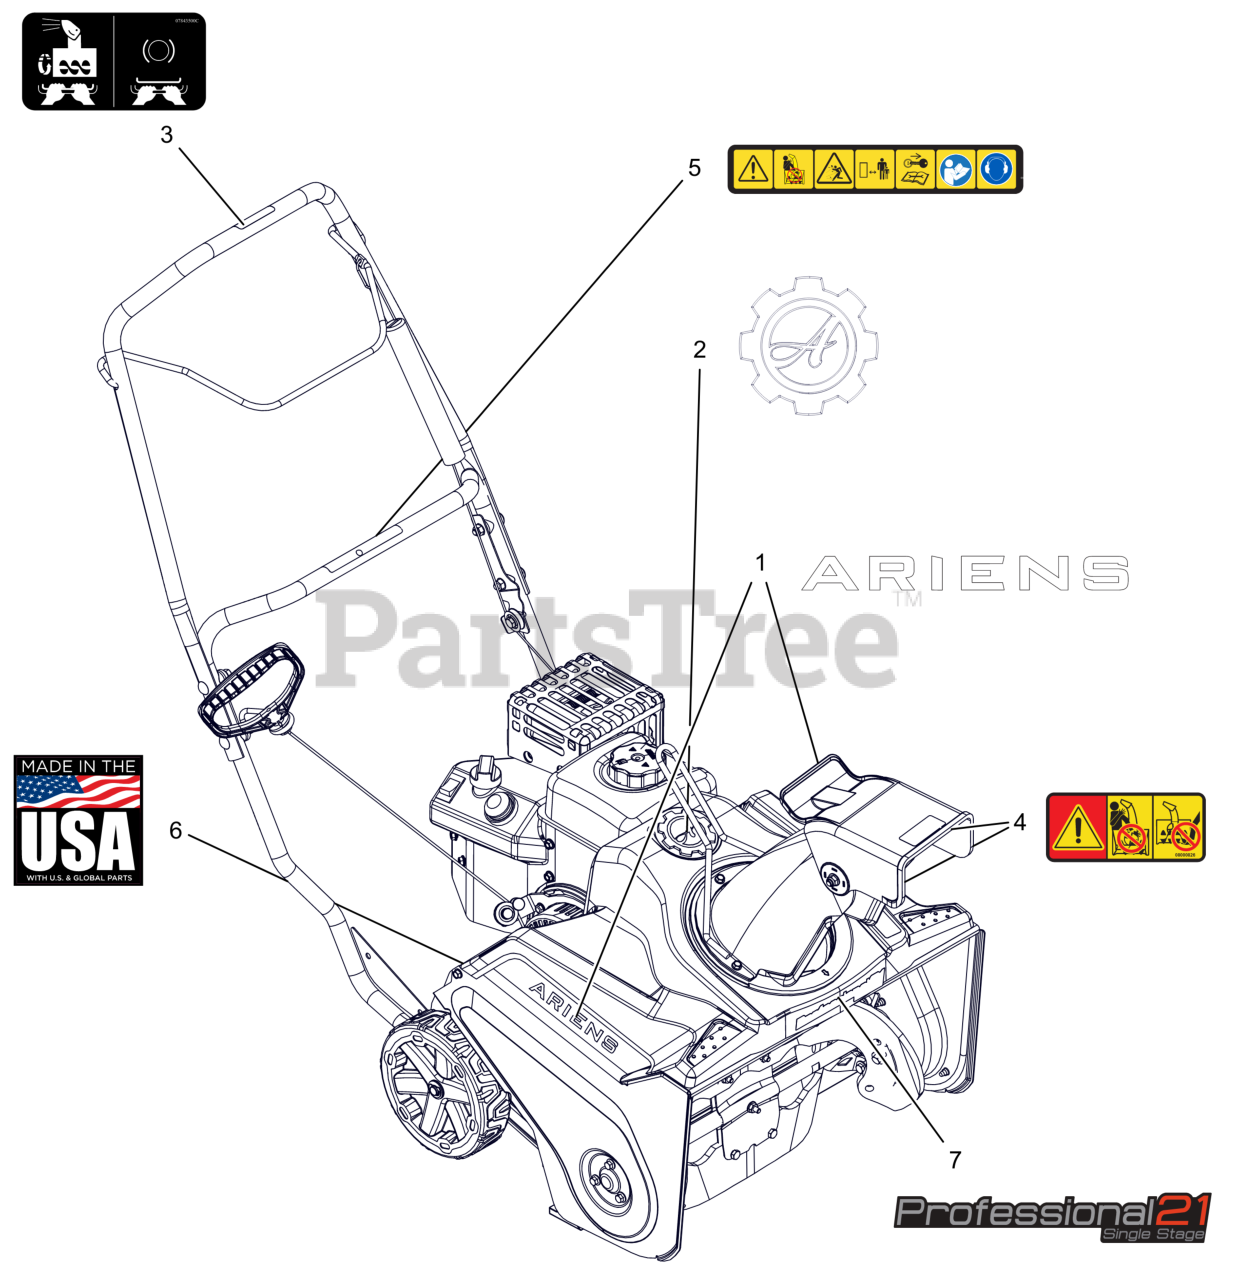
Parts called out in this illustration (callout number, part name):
1	DECAL, ARIENS (6.50")
2	DECAL, ARIENS-GEAR BADGE -THK
3	DECAL-AUGER/IMPELLER BAIL
4	DECAL, DANGER SINGLE STAGE
5	DECAL,DASH - SAFETY
6	DECAL, MADE IN USA
7	DECAL,COVER - PRO 21" CSS
